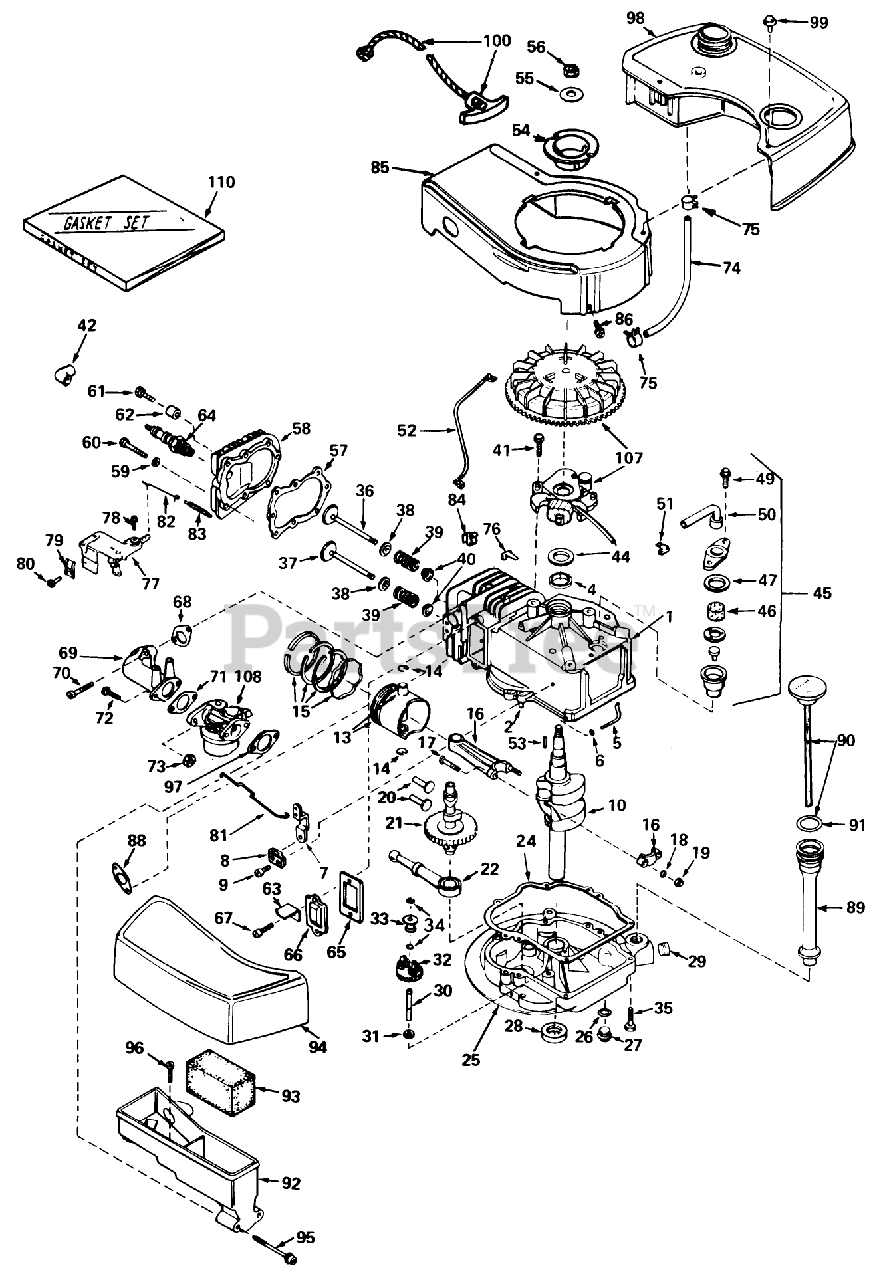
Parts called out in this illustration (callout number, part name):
1	Cylinder Assy. (Incl. Ref. #2, 4 105)
2	Pin-Dowel
4	OIL SEAL
5	Rod, Governor (Incl. No. 36)
6	Washer-Flat
7	Governor Lever
8	Clamp-Lever, Governor
9	Screw
10	Crankshaft
13	Piston Pin Assembly (Incl. 2 of No. 14) (.010 Oversize)
13	Piston Pin Assembly (Incl. 2 of No. 14) (.020 Oversize)
14	Ring-Retaining, Piston Pin
15	Ring Set Piston (Std.)
15	Ring Set Piston (.010 Oversize)
15	Ring Set Piston (.020 Oversize)
16	Rod Assy., Connecting (Incl. Ref. #17)
17	Bolt, Connecting
18	Washer
19	LOCKNUT
20	Lifter-Valve
21	Camshaft(Mech.Comp. Release)
22	Oil Pump ASM
24	Gasket, Mounting
25	Filter, Air Cleaner
26	Gasket-Oil Drain
27	Plug Oil Drain
28	Seal Oil
29	Plug Oil Drain
30	Shaft-Governor
31	Washer-Flat
32	Governor Gear ASM
33	Spool-Governor
34	Ring-Retaining
35	Screw (1/4-20 x 1-1/4)
36	Valve, Intake (Incl. Ref. #38, 39 40) (Std.)
36	Valve, Exhaust (1/32" Oversize) (Incl. Nos. 8, 9 10)
37	Valve, Exhaust (Standard) (Incl. Nos. 8, 9 10)
37	Valve, Exhaust (1/32" Oversize) (Incl. Nos. 8, 9 10)
38	Cap-Upper Valve Spring
39	Spring-Valve
40	Cap-Valve, Spring
41	Screw
42	Cover-Spark Plug
44	Gasket Stator
45	Breather Assy. (Incl. Ref. #46, 47, 49, 50 51 )
46	Element-Breather
47	Gasket-Breather
49	Screw, Hex Hd. w/Conical
50	Tube, Breaker
51	Clip, Breather
52	Wire, Ground
53	Key-Flywheel
54	Pulley Starter
55	Washer-Spring
56	Hex Nut
57	63573 GIL 42 SNWTHW
58	Head Cylinder
59	Washer
60	Screw
61	Screw Hex Hd. Cap
62	Space
63	Retainer Clip
64	Plug, Spark (J17LM or equiv.)
65	Gasket-Breather
66	Cover-Valve
67	Screw
68	Gasket, Intake
69	Pipe, Intake
70	Screw (1/4-20 x 1)
71	Gasket-Carburetor
73	Nut and Lock Washer (1/4-28)
74	Line-Fuel
75	Clamp-Line, Fuel
76	Clip-Wire
77	Control Assy., Speed (Incl. Nos, 76, 78 89)
78	Screw (10-24 x 3/4)
79	Conduit
80	Screw (10-32 x 3/8)
81	Link Governor
82	Link Governor Spring
83	Spring Governor
84	51004 GIL ROTARY TI
85	53024/VAR.GT O/P W/
86	Screw
88	Gasket Exhaust
89	Tube Fill
90	Dipstick, Oil (Incl. Ref. #101)(Twist Lock)
91	O-Ring
92	Body Air Cleaner
93	Filer, Air
94	Cove, Air Cleaner
95	Screw Fil Hd.
96	Screw, Hex Hd.
97	Gasket-Air Cleaner
98	Tank Fuel
99	Screw (10-32 x 35/64)
100	Rope Assy., Starter
107	Magneto
108	Carburetor (Incl. No. 71)
110	53024/VAR.16HP O/P
